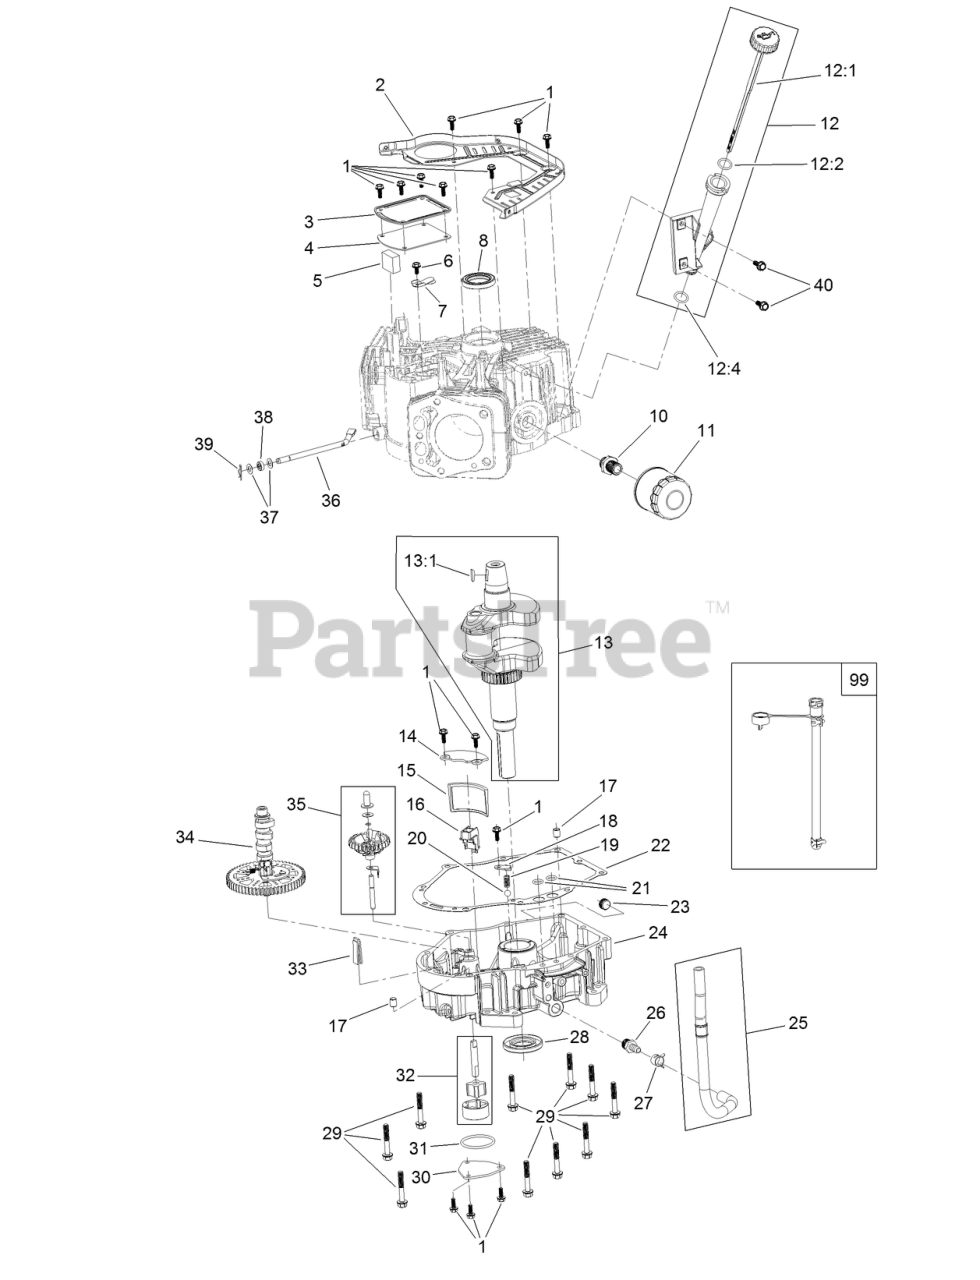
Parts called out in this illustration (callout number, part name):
1	SCREW-HHF
2	BAFFLE
3	COVER-BREATHER
4	GASKET-BREATHER
5	FILTER-BREATHER
6	SCREW-HHF
7	VALVE-BREATHER
8	SEAL-OIL
10	ADAPTOR-FILTER, OIL
11	FILTER-OIL
12	OIL TUBE ASM
12:1	DIPSTICK
12:2	O-RING
12:4	O-RING
13	CRANKSHAFT
13:1	KEY-WOODRUFF
14	COVER-SCREEN, OIL
15	SCREEN-OIL
16	RETAINER-SCREEN
17	PIN-DOWEL
18	PLATE-RETAINER
19	SPRING
20	VALVE-BALL
21	O-RING
22	GASKET-COVER, CRANKCASE
23	PLUG-DRAIN
24	COVER-CRANKCASE
25	OIL DRAIN HOSE ASM
26	FITTING-HOSE
27	CLAMP-HOSE
29	SCREW-HHF
30	COVER-OIL PUMP
31	O-RING
32	OIL PUMP ASM
33	DEFLECTOR-OIL, RUBBER
34	CAMSHAFT
35	GOVERNOR ASM
36	SHAFT-GOVERNOR
37	WASHER-PLAIN
38	SEAL-OIL
39	PIN-HAIR
40	SCREW-HHF
99	OIL DRAIN SERVICE KIT
